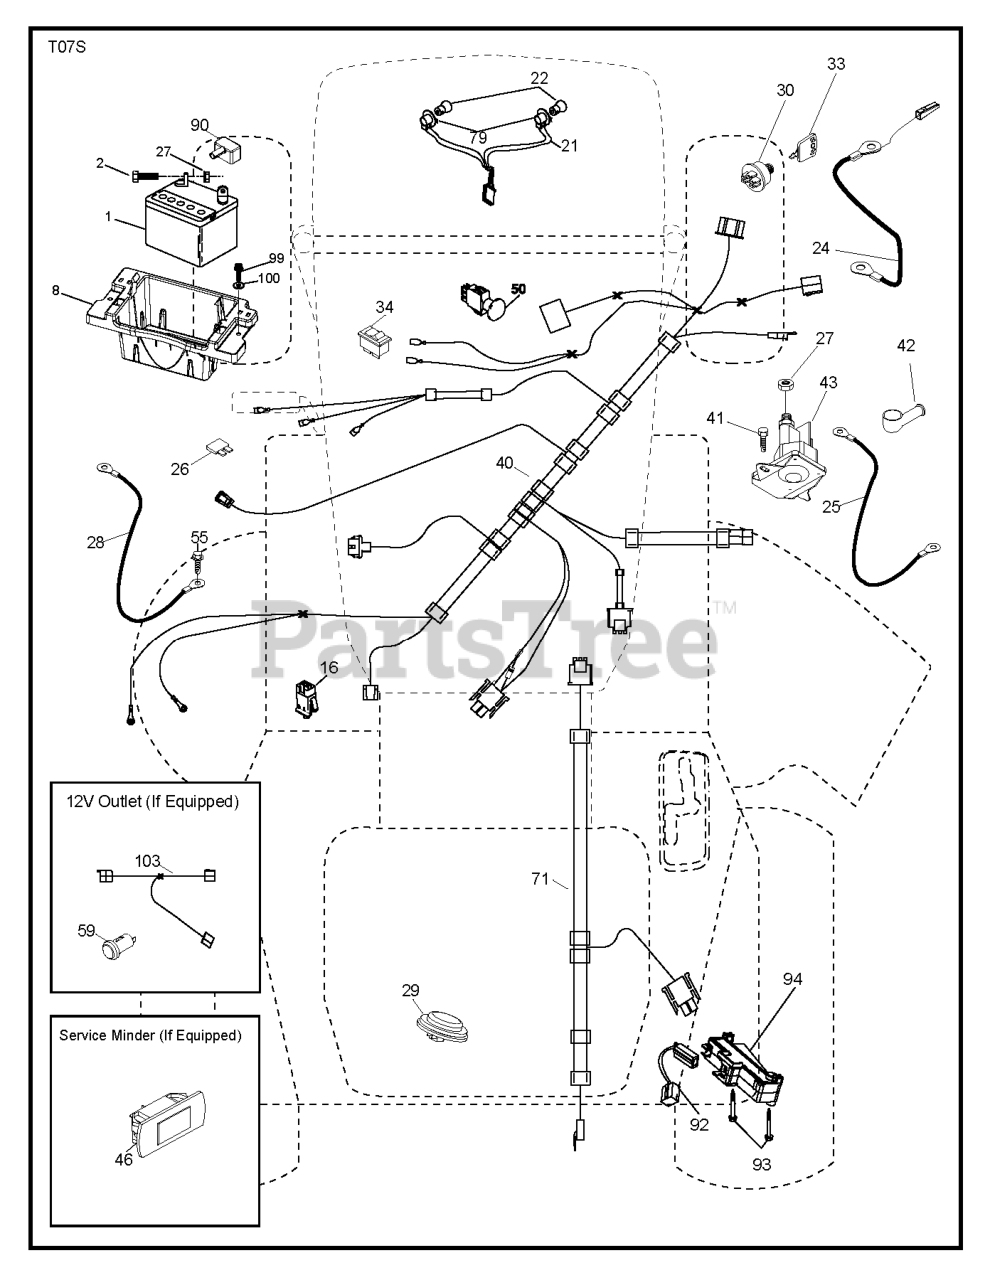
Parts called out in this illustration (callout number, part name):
1	Battery 12 Volt 25 Amp
2	BOLT.HEX.1/4.X.3/4.DICHROMATE
8	TRAY.BATTERY.BOX.FRONT
16	SWITCH INTERLOOK PUSH-IN
21	HARNESS.LIGHT W/4152J BULBS
24	CABLE.FRBATT.W/WIRE.8GA.8
25	CABLE.STARTER.8GA.17.5
26	FUSE 20AMP
27	NUT
28	CABLE.GROUND.21"BLK.8GA.90T
29	SWITCH.SEAT.DELTA.OPC.
30	SWITCH.IGN.DELTA.W.LGH.ROS
33	KEY.CHAIN.BLISTER.PACK.GEN.USA
40	HARNESS HARNESS..DASH.ING.ELEC
41	SCREW
42	TERMINAL COVER
43	SOLENOID.STARTER.BRASS.PLUNGER
46	GUAGE.SRVCMNDR.HRMTR.
50	SWITCH.PTO.8TERMINAL.STD.BLK
55	SCREW 5/16"
59	OUTLET.12-VOLT
71	HARNESS-CHASSIS SUB
79	BULB HOLDER ASM.
90	COVER.TERMINAL.BATTERY
92	HARNESS.PIGTAIL.CONSLE
93	SCREW.PLASTITE
94	MODULE.REVERSE.ROS
99	SCREW HEXWSHR 1/4-20X3/4
100	WASHER
103	HARNESS PIGTAIL 12V OUTLET
